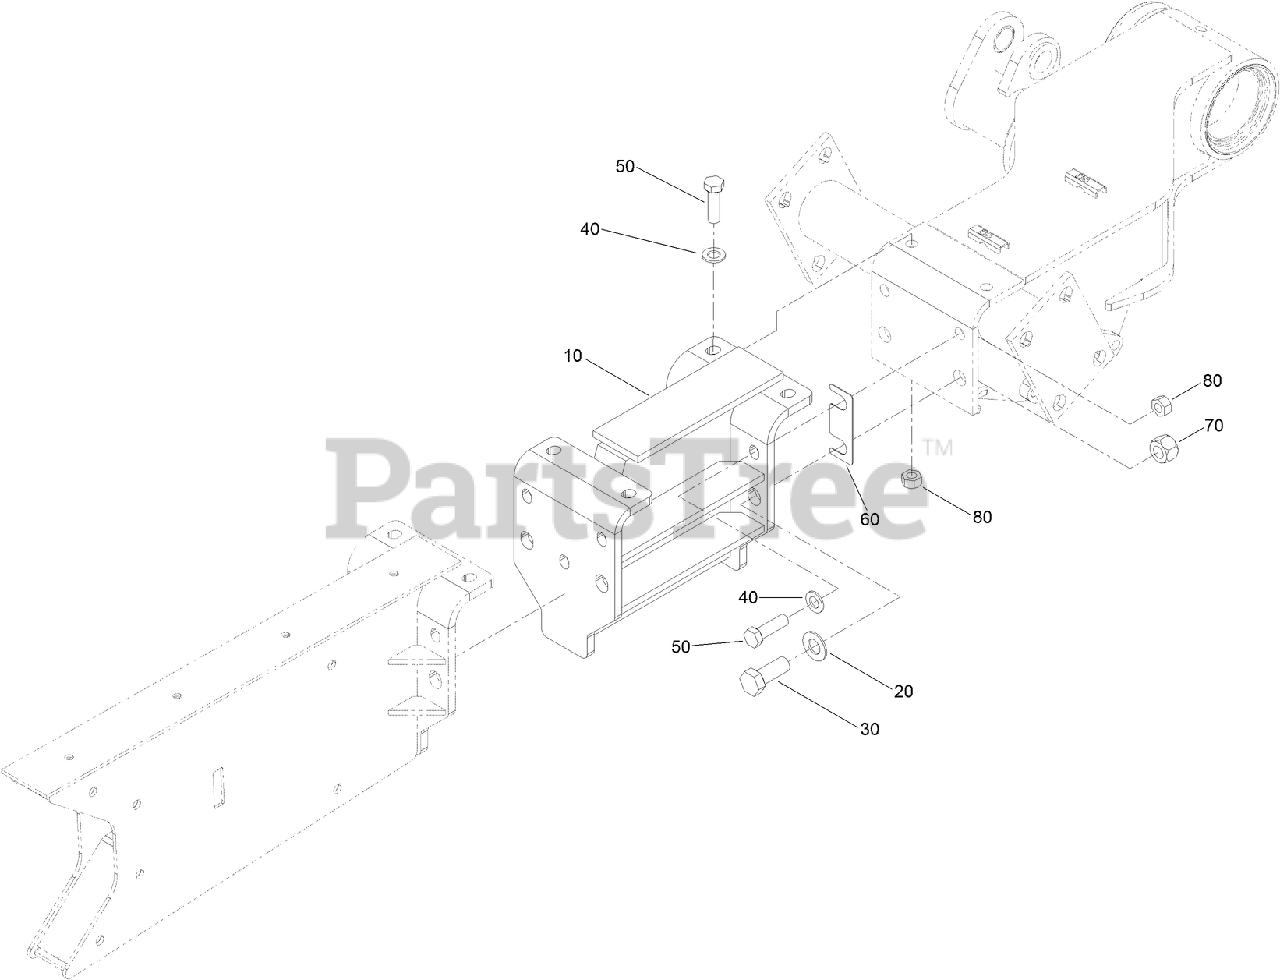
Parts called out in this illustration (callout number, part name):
10	EXTENSION-ROCK BOOM, 12 INCH
20	WASHER-FLAT
40	WASHER-FLAT
80	NUT-LOCK
